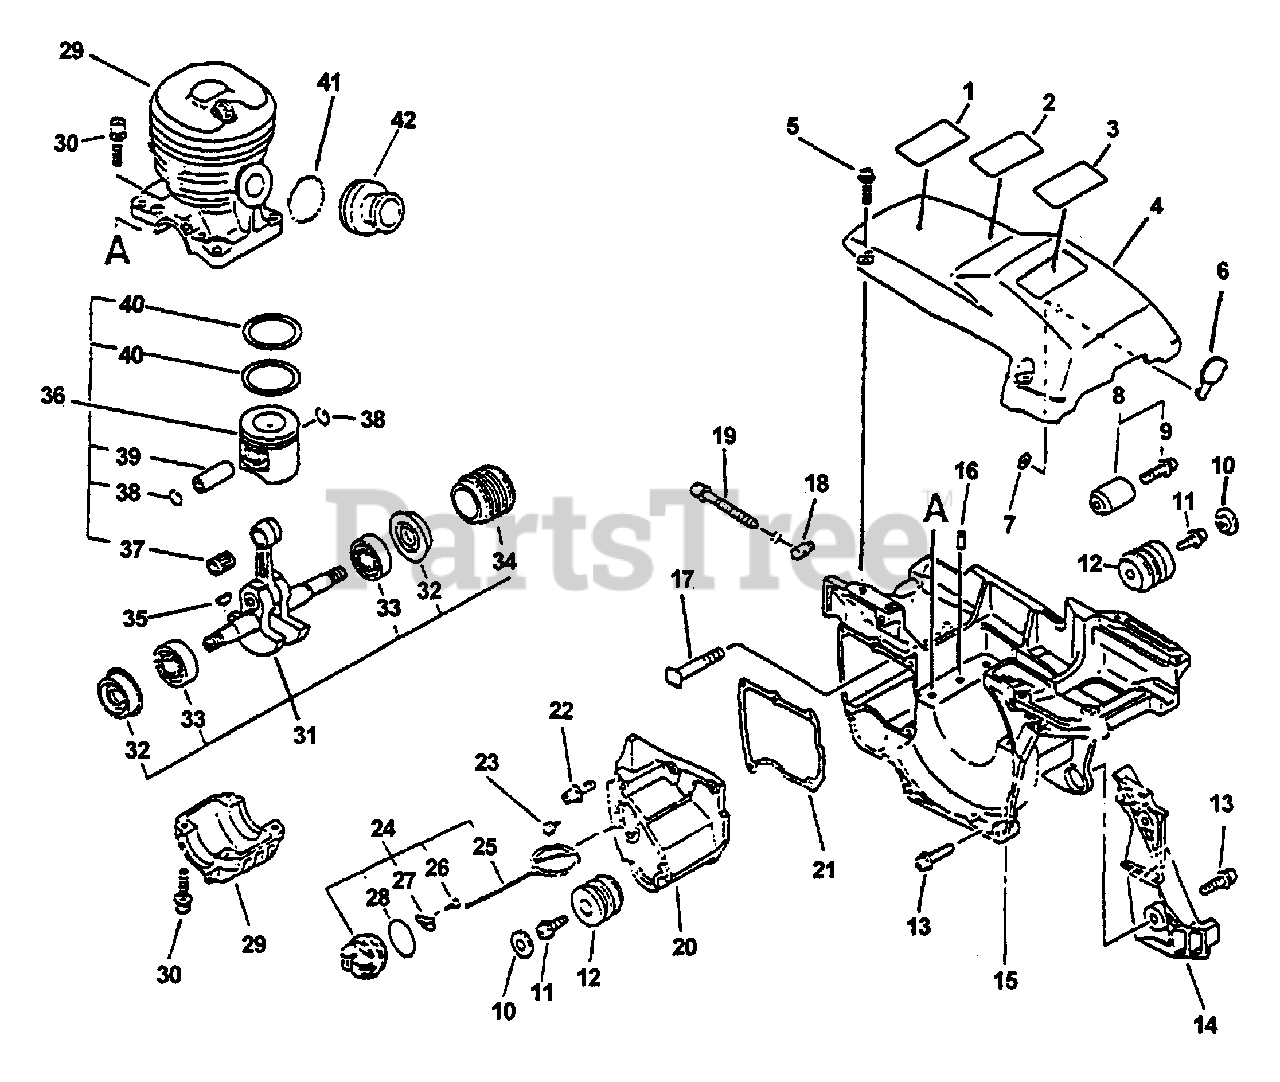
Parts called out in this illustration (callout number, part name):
1	LABEL - KICK BACK
2	LABEL - BAR & CHAIN
3	LABEL - MODEL CS-4400
4	COVER, ENGINE
5	SCREW - 5
7	PUSHNUT - 4
8	CHAIN CATCHER KIT
9	SCREW - 5X18
10	CAP, CUSHION
13	SCREW - 5X16
15	COVER, ENGINE
16	PIN - LOCATING
17	STUD, GUIDE BAR
18	TENSIONER, CHAIN
19	SCREW, TENSIONER
20	OIL TANK ASSY
21	GASKET, OIL TANK
22	SCREW - 4X16
23	VENT, TANK
24	CAP ASSY
25	CONNECTOR, CAP
26	SCREW - 3X8
27	RETAINER
28	O-RING - 25
29	CRANKCASE KIT
30	SCREW - 5X22
31	CRANKSHAFT ASSY
32	SEAL, OIL
33	BEARING, BALL - 6201
34	GEAR - WORM
35	KEY
36	PISTON KIT
37	BEARING, NEEDLE
38	RING, RETAINING
39	PIN, PISTON
40	RING, PISTON
42	ADAPTOR, INTAKE
